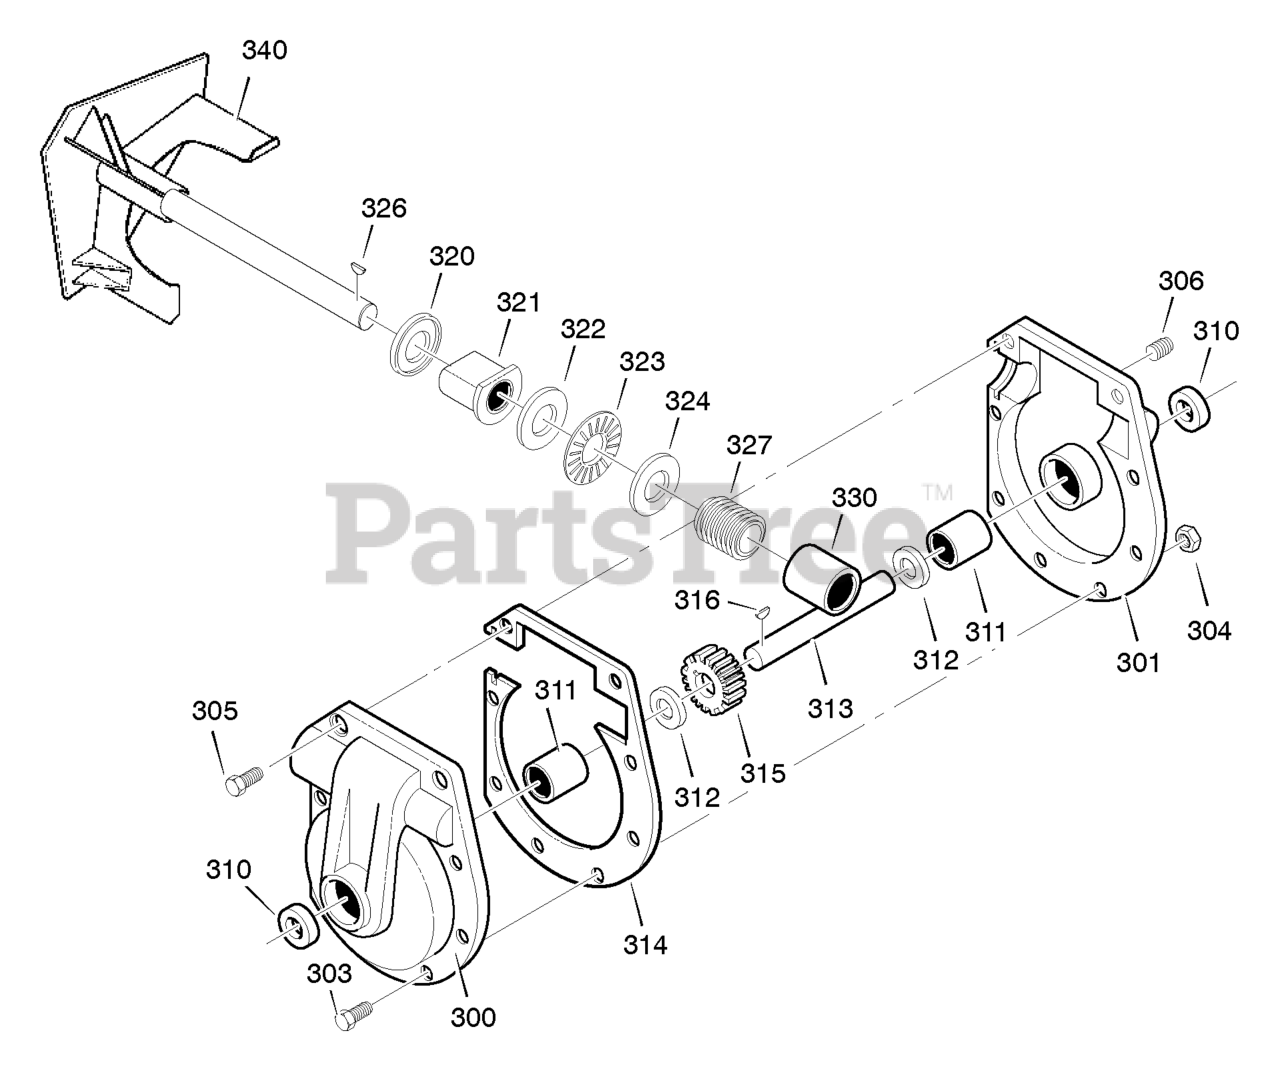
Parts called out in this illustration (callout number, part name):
300	CASE, GEAR, RH
301	CASE, GEAR, LH
303	SCREW, 5/16-24 x 1.00
304	NUT, 5/16-24
305	SCREW, 5/16-24 X 1.50
306	PLUG, PIPE
310	SEAL, OIL
311	BEARING
312	WASHER, FLAT
313	SHAFT, AUGER OUTPUT
314	GASKET, GEAR BOX
315	WORM GEAR
316	KEY, WOODRUFF #91
320	RING, QUAD
321	BEARING, FLANGE
322	WASHER, FLANGE
323	BEARING, ROLLER
324	WASHER, FLAT
327	GEAR, WORM
330	BEARING
340	IMPELLER
